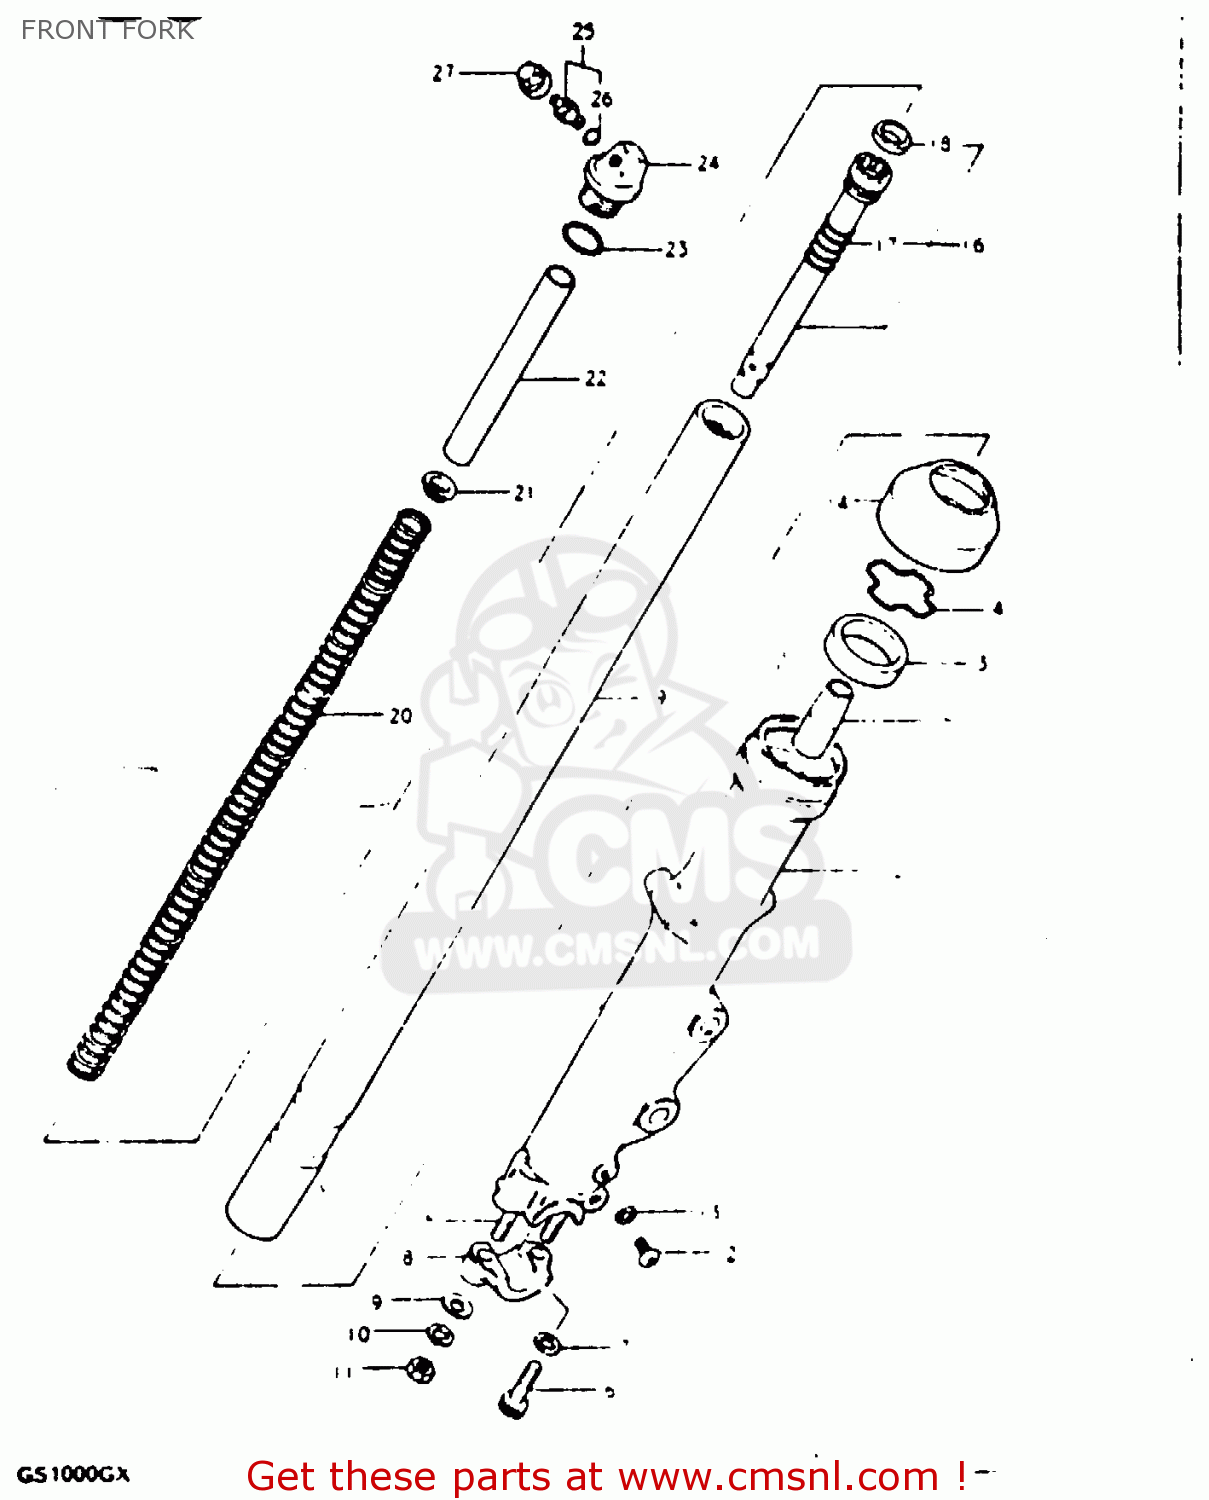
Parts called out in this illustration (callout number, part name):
1	TUBE,FORK,OUTER,RIGHT
2	TUBE,FORK,LEFT,OUTER
3	OIL SEAL,FRONT FORK
4	RING,STOPPER
5	STUD BOLT
6	BOLT,FORK CYLINDER(10X25)
7	GASKET (NAS)
8	HOLDER,AXLE
9	WASHER
10	LOCK WASHER
11	NUT (8MM)
12	SCREW
13	GASKET,DRAIN,PLUG (NAS)
14	SEAL,DUST
15	PIECE,OIL LOCK
16	CYLINDER,FRONT FORK
17	SPRING,REBOUND
18	RING,PISTON
19	TUBE,FORK,INNER
20	SPRING,FRONT FORK
21	GUIDE,FRONT FORK SPRING C
22	SPACER,SPRING
23	O RING
24	CAP
25	VALVE
26	O RING
27	CAP,VALVE
